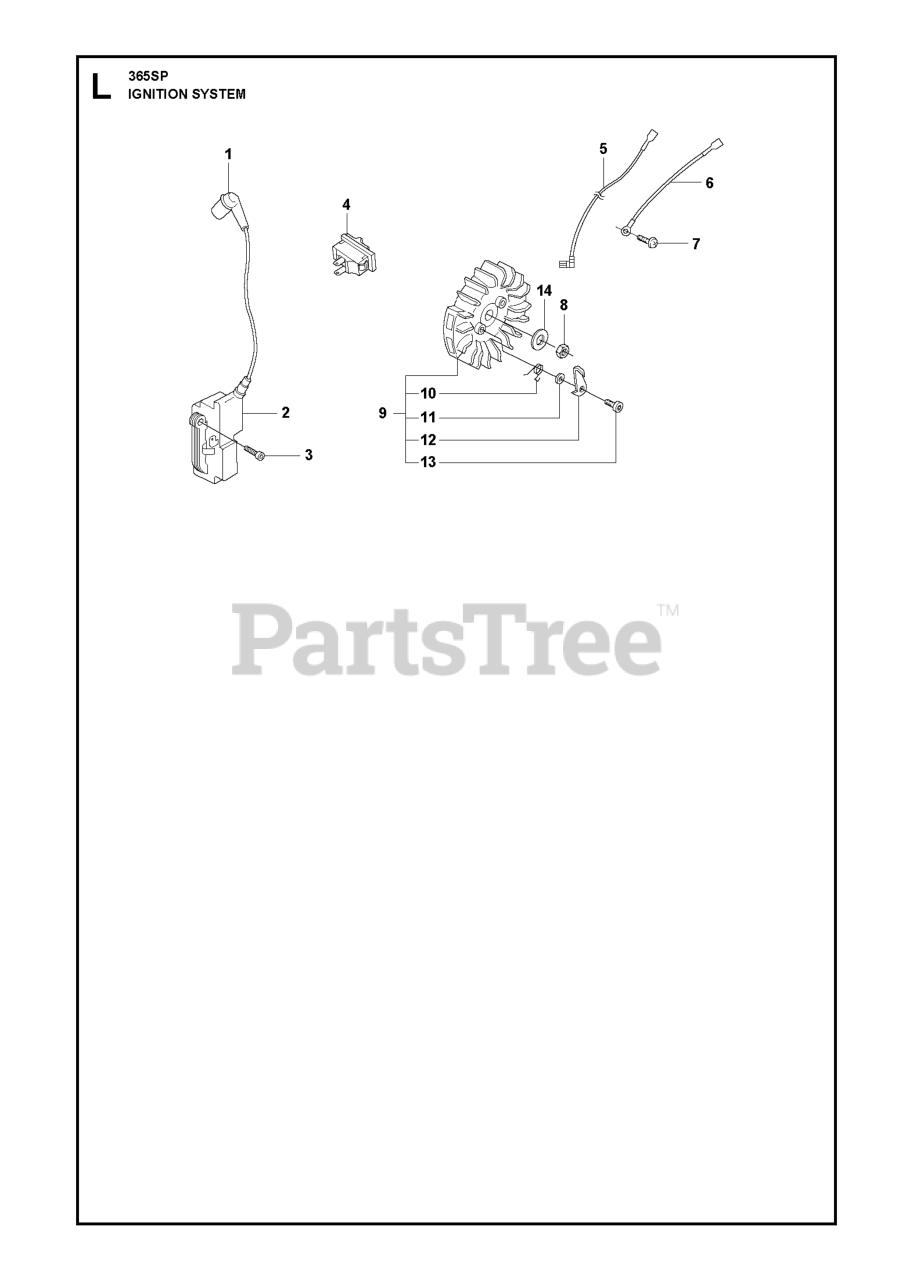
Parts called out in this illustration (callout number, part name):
1	SPARK PLUG CONN. KIT
2	IGNITION MODULE
3	SCREW IHSCM M5X20 12.9 TBO SE
4	START/STOP SWITCH
7	SCREW CITXPANT
13	SCREW M5X14
14	WASHER 8.4X16
